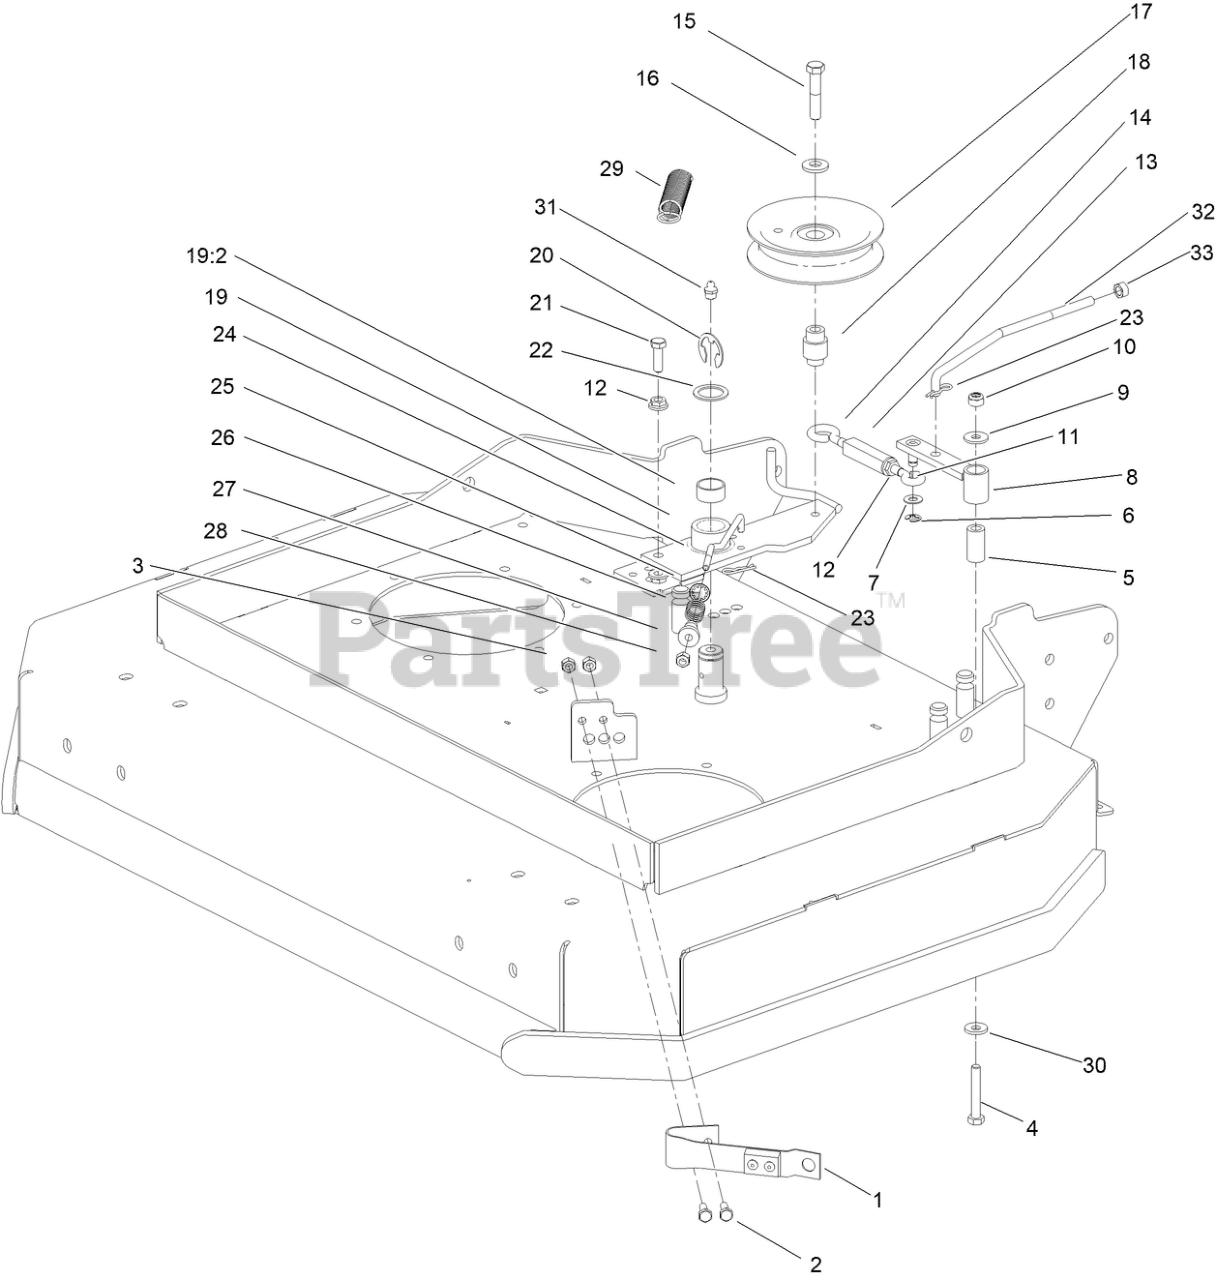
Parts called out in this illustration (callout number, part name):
1	PAD AND SPRING ASM
2	SCREW-HH
3	NUT-LOCK, NI
4	SCREW-HH
5	TUBE-PIVOT
6	RING-RETAINING, EXT
7	WASHER
8	ARM-ASSIST, 32/36
9	WASHER
10	NUT-NYLOC
11	EYEBOLT-THREAD, RH
12	NUT-HF
13	BODY-TURNBUCKLE
14	EYEBOLT-THREAD, LH
15	SCREW-HH
16	WASHER-BELLEVILLE
17	PULLEY-IDLER, FLAT
18	BUSHING-ENGAGEMENT
19	IDLER ARM ASM
19:2	SLEEVE-BEARING
20	RING-RETAINING, EXT
21	SCREW-HH
22	WASHER-SPINDLE
23	PIN-COTTER
24	ROD-BRAKE
25	RING-PUSH ON
26	SPRING-COMPRESSION
27	SPACER-FLANGED
28	NUT-LOCK, NI
29	SPRING-EXTENSION
30	WASHER-SPRING
31	FITTING-STRAIGHT
32	ROD-LINKAGE, DRIVE
